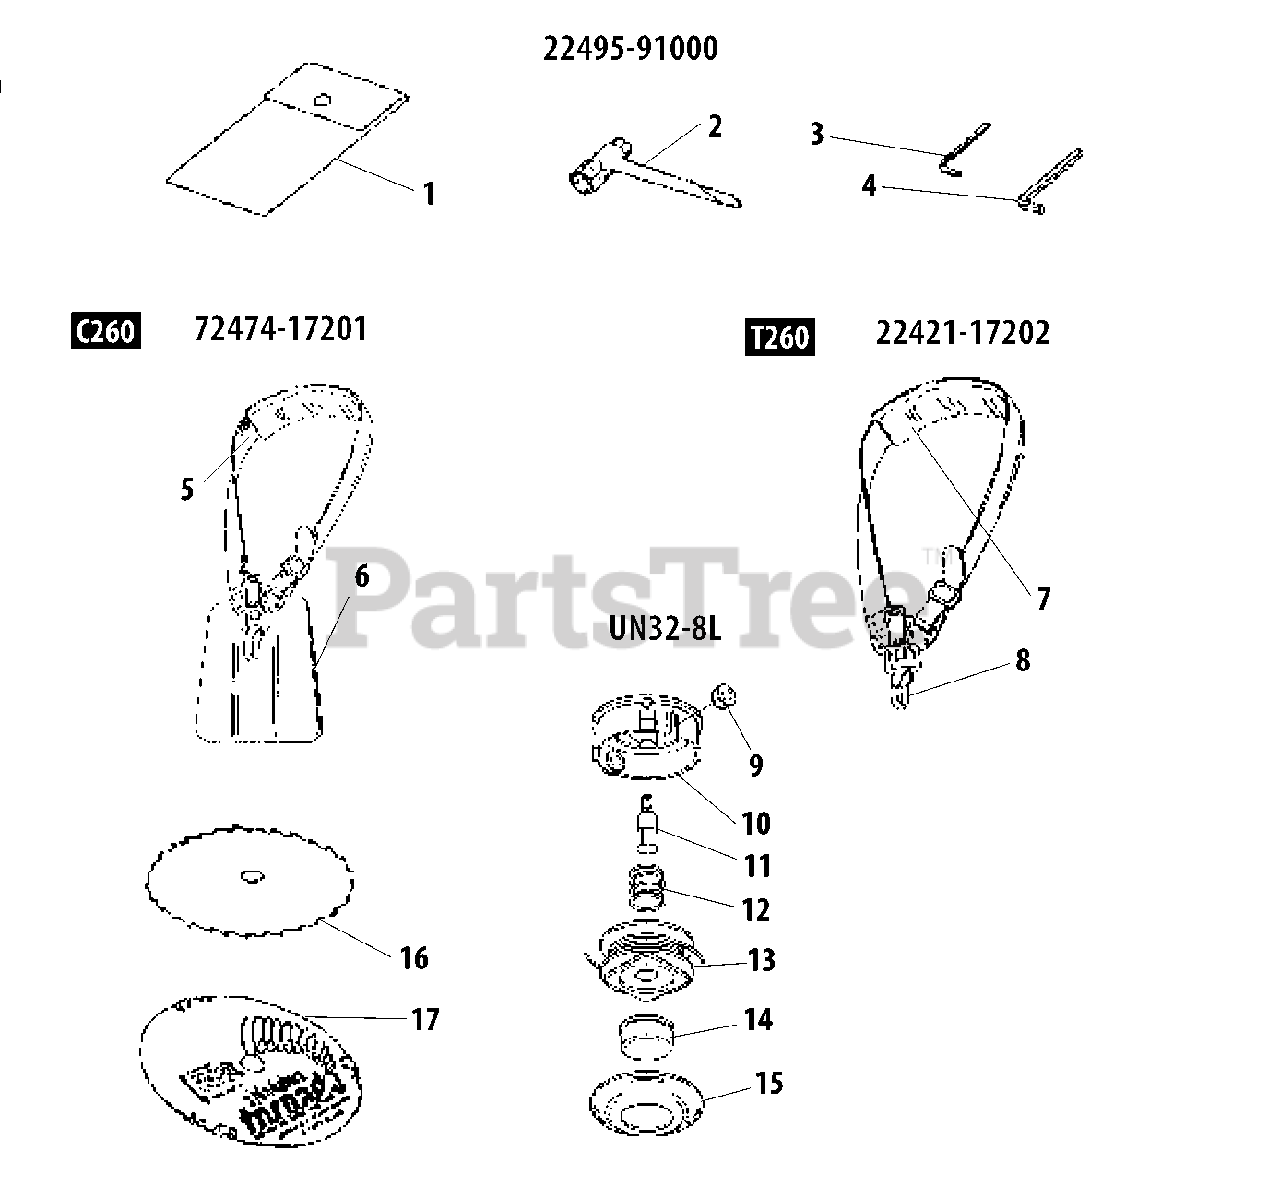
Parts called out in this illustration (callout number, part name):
1	BAG, TOOL
2	T-WRENCH - 13X19mm
3	HEX KEY - 3mm
4	HEX KEY - 4mm
5	PAD
6	PAD
7	PAD
8	HOOK
11	SHAFT BOLT
16	BLADE, 30 TOOTH - 25mm -- 8"
17	BLADE - 6 TOOTH -- 9" (22cm)
A	TOOL KIT
A	HARNESS ASSY
A	TRIMMER HEAD ASSY
